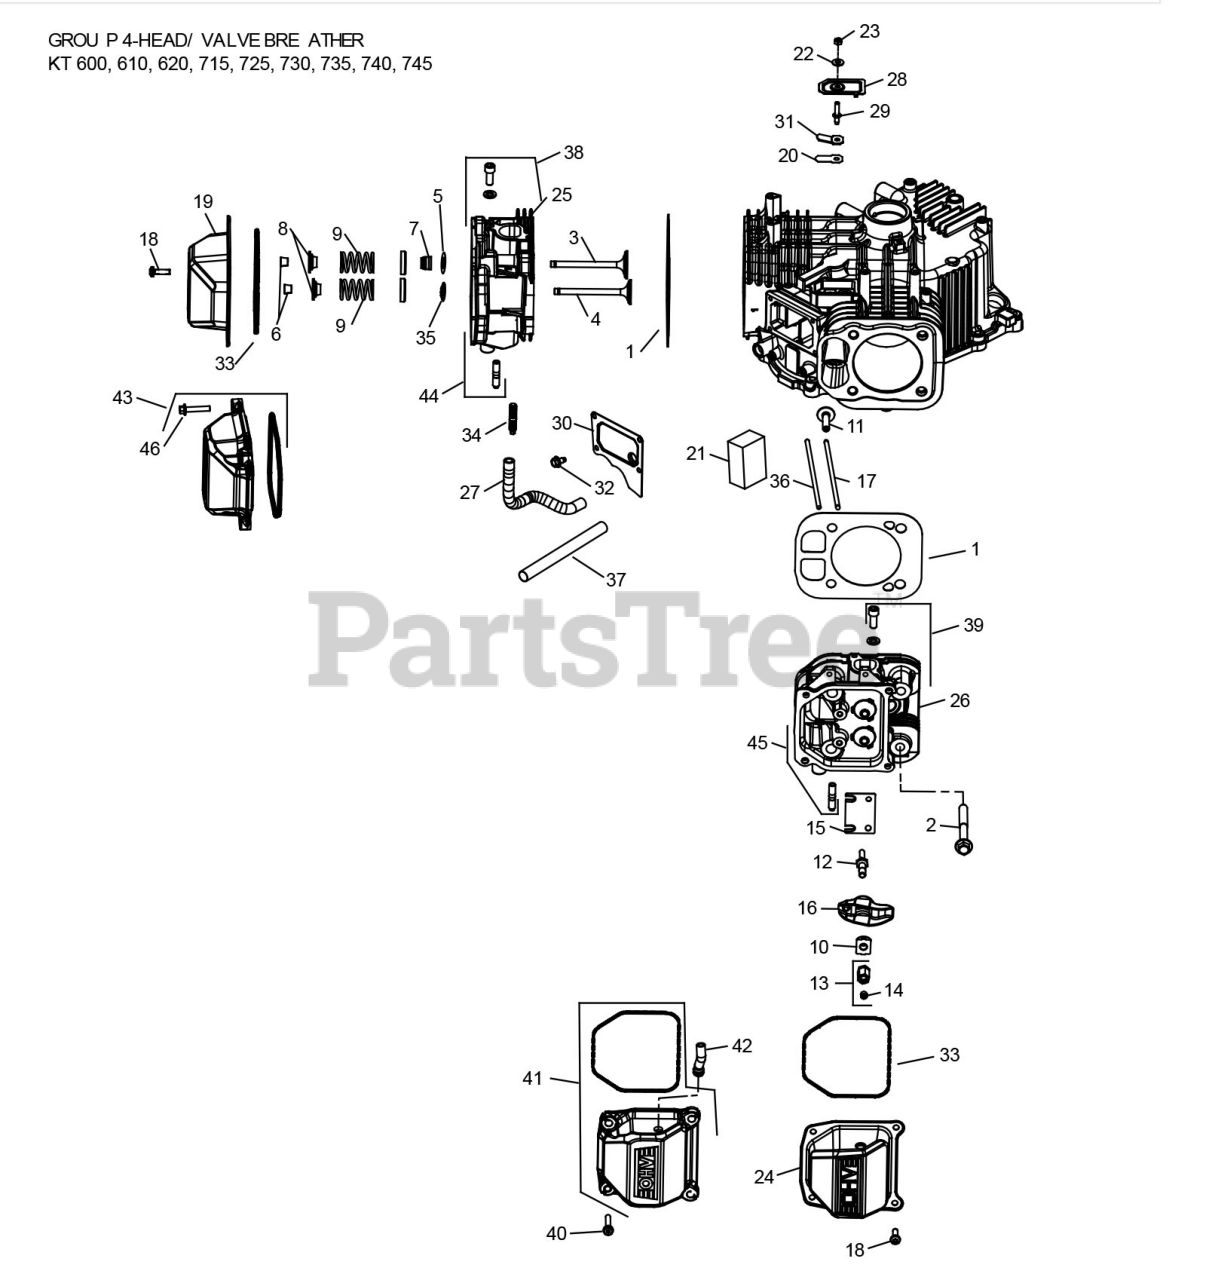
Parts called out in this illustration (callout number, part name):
1	GASKET KIT-CYL HEA
3	INTAKE VALVE .25
4	EXHAUST VALVE
4	EXHAUST VALVE .25
6	KIT-RETAINER
7	VALVE STEM SEAL
8	VALVE CAP SPRING
10	PIVOT- ROCKER ARM
11	TAPPET-PUSH ROD
13	NUT ASSEMBLY-ROCKER
20	BREATHER REED
21	BREATHER FILTER
22	SEALING WASHER
27	BREATHER HOSE
28	COVER-BREATHER REED
29	STUD-BRETHR REED C
30	COVER-BREATHER FILTE
31	RETAINER-BREATHER
33	O-RING VLV CVR
35	VALVE GUIDE RETAINER
41	KIT-ROCKER COVER
42	HOSE KIT-FUEL PUMP
43	COVER KIT-ROCKER
